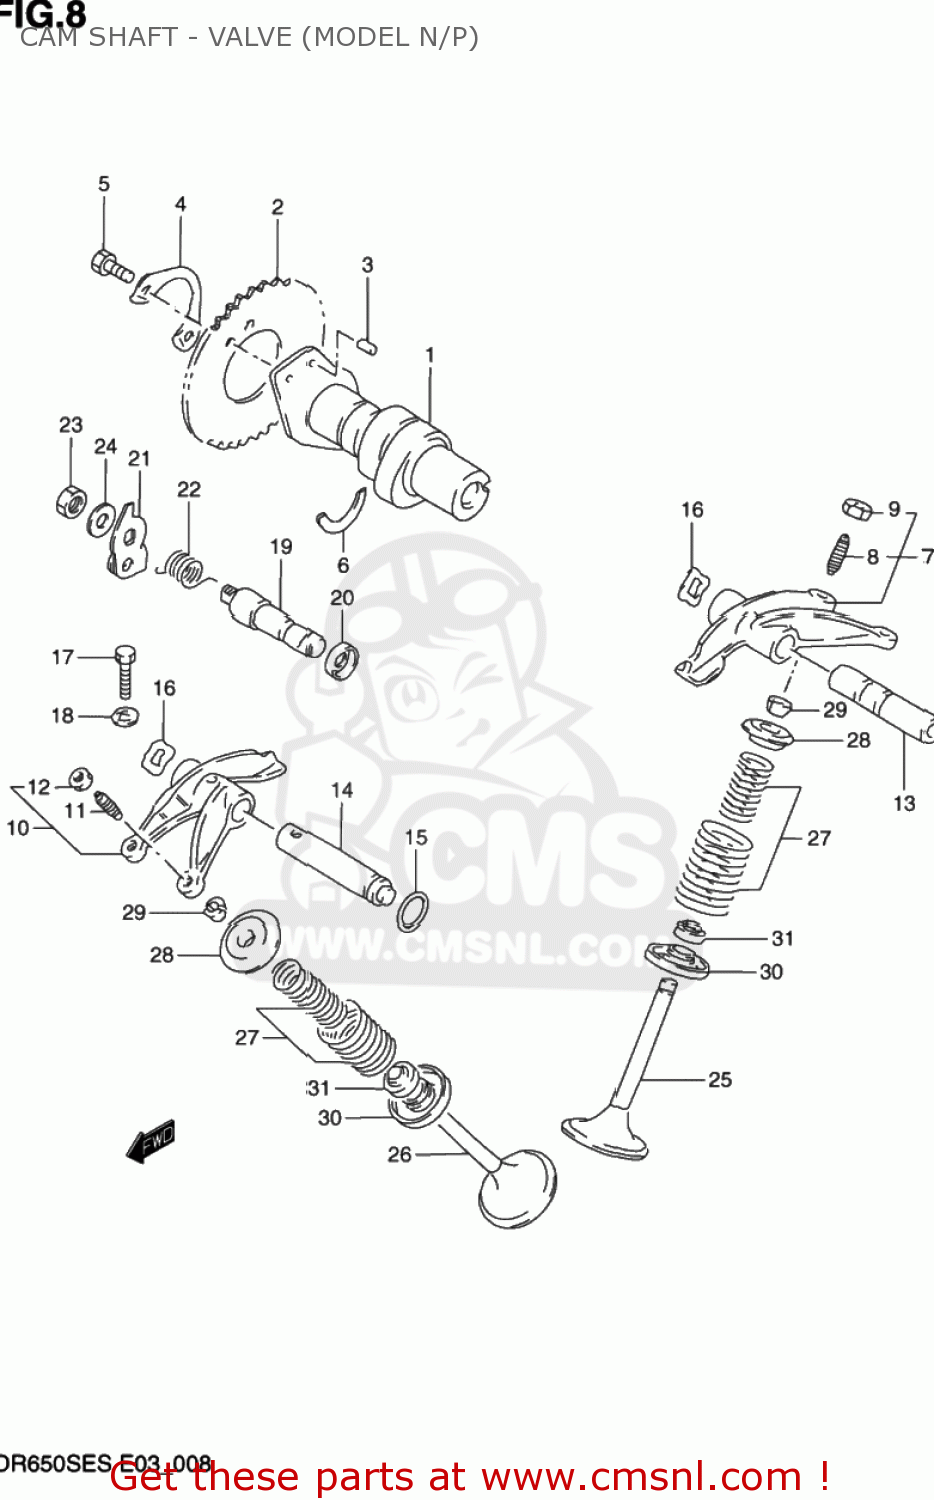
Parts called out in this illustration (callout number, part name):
1	CAMSHAFT
2	SPROCKET,CAMSHAFT(NT:42)
3	PIN
4	WASHER,CAM CHAIN SPROCKET
5	BOLT(6X12.5)
6	C RING
7	ARM,VALVE ROCKER INTAKE
8	SCREW,TAPPET ADJUSTING
9	NUT,ADJUSTING SCREW
10	ARM,VALVE ROCKER EXHAUST
11	SCREW,TAPPET ADJUSTING
12	NUT,ADJUSTING SCREW
13	SHAFT,VALVE ROCKER ARM INTAKE
14	SHAFT,EXHAUST VALVE ROCKER ARM
15	O RING(D:1.9,ID:8.6)
16	WASHER
17	BOLT 6X30
18	GASKET(5.8X13X1.2) (NAS)
19	SHAFT,DECOMPRESSION
20	SEAL,OIL(10X17X6)
21	LEVER,DECOMP SHAFT
22	SPRING,DECOMPRESSION SHAFT LEVER
23	NUT 8MM
24	WASHER
25	VALVE,INTAKE
26	VALVE,EXHAUST
27	SPRING SET,VALVE
28	RETAINER,VALVE SPRING
29	COTTER VALVE
30	SEAT,VALVE SPRING
31	SEAL,OIL(7X14.4X9)
